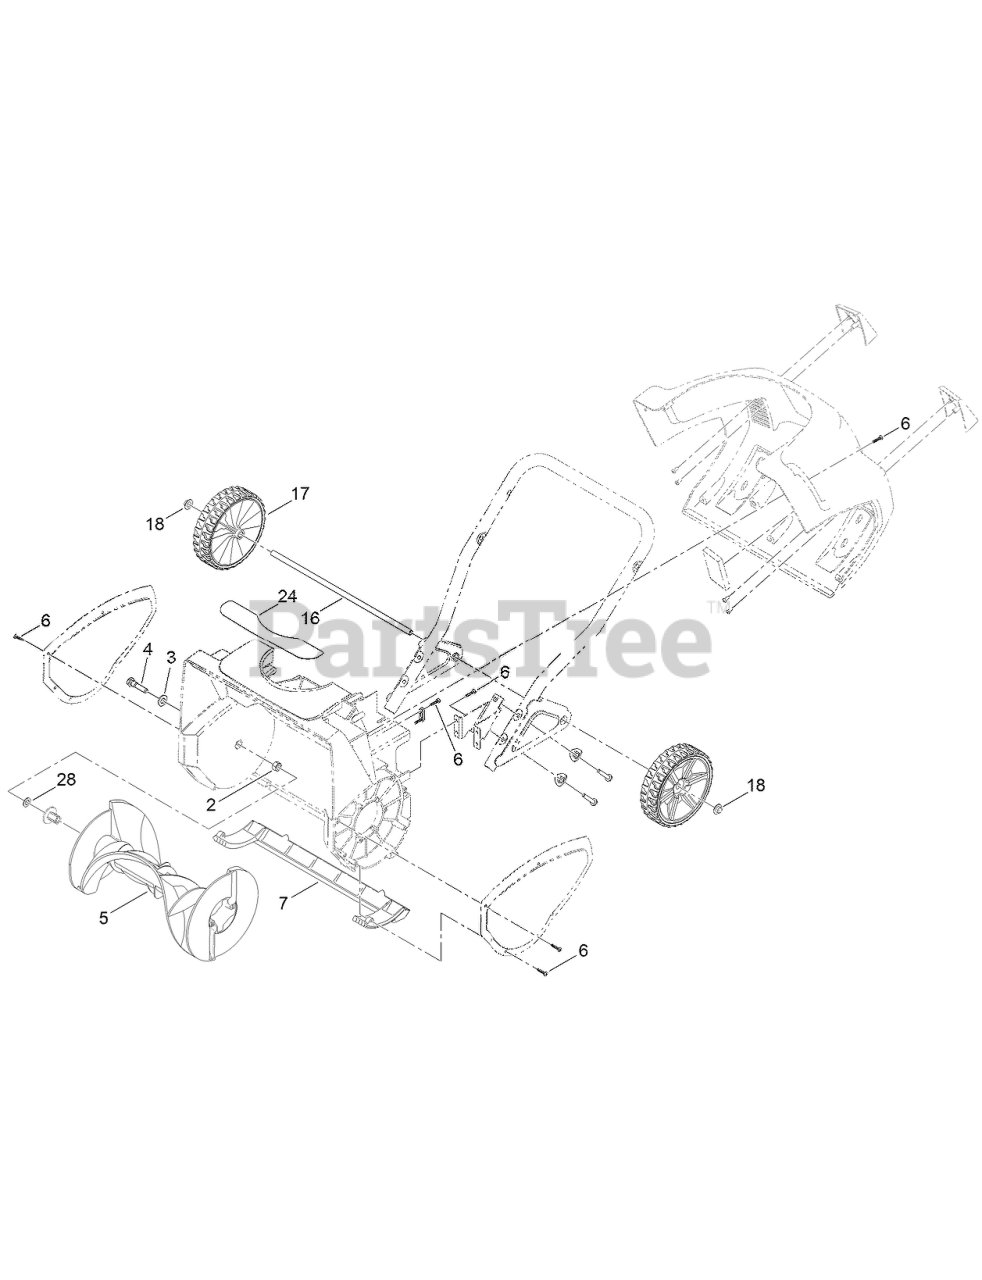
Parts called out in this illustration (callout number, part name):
2	NUT-LOCK
3	WASHER-FLAT
4	PIN-ROTOR
5	ROTOR ASM
6	SCREW-PPH
7	SCRAPER
16	AXLE-WHEEL
17	WHEEL ASM
18	RETAINER-PUSH ON
28	WASHER
